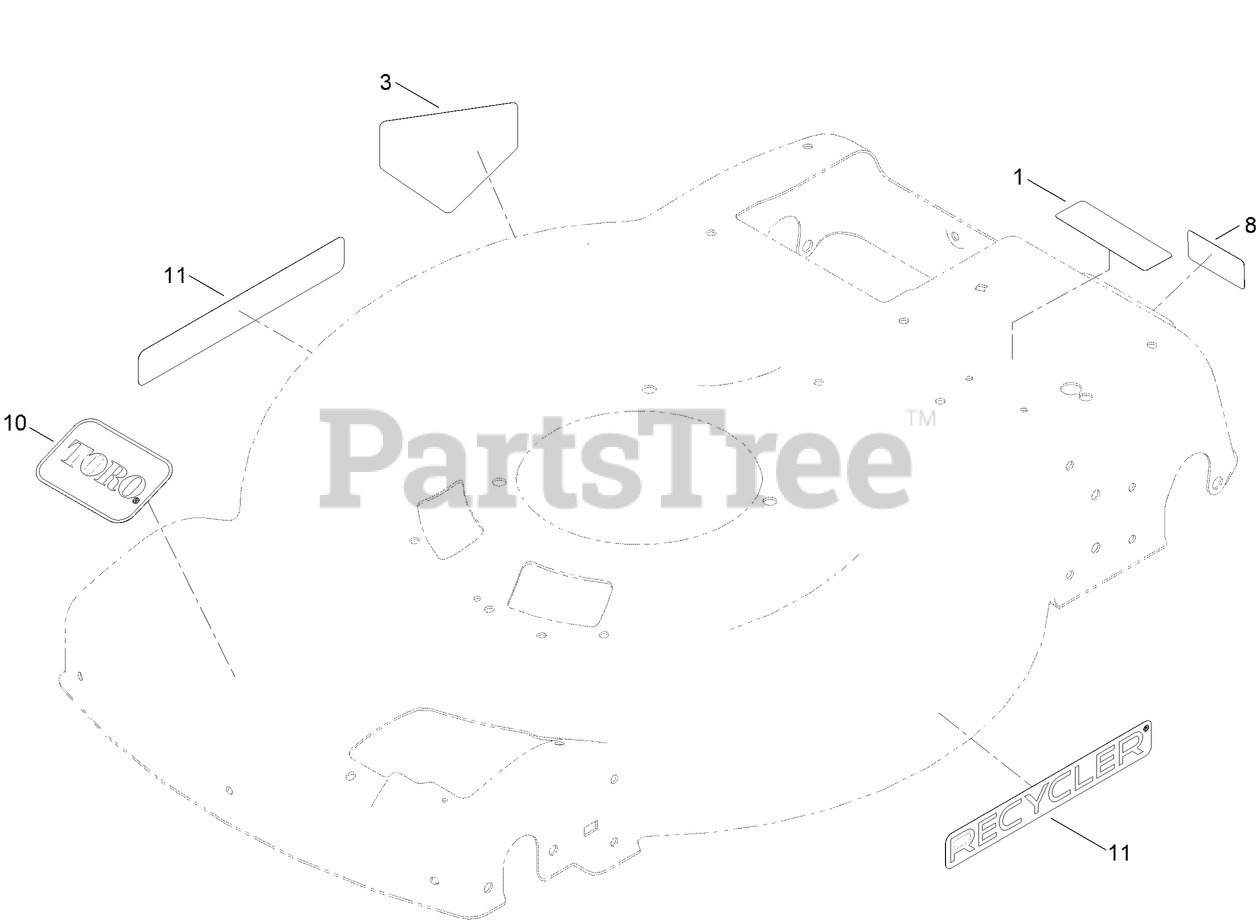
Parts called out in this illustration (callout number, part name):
1	DECAL-MODEL/SERIAL
3	DECAL-DANGER
8	DECAL-LOCATION, SERVICE DEALER
